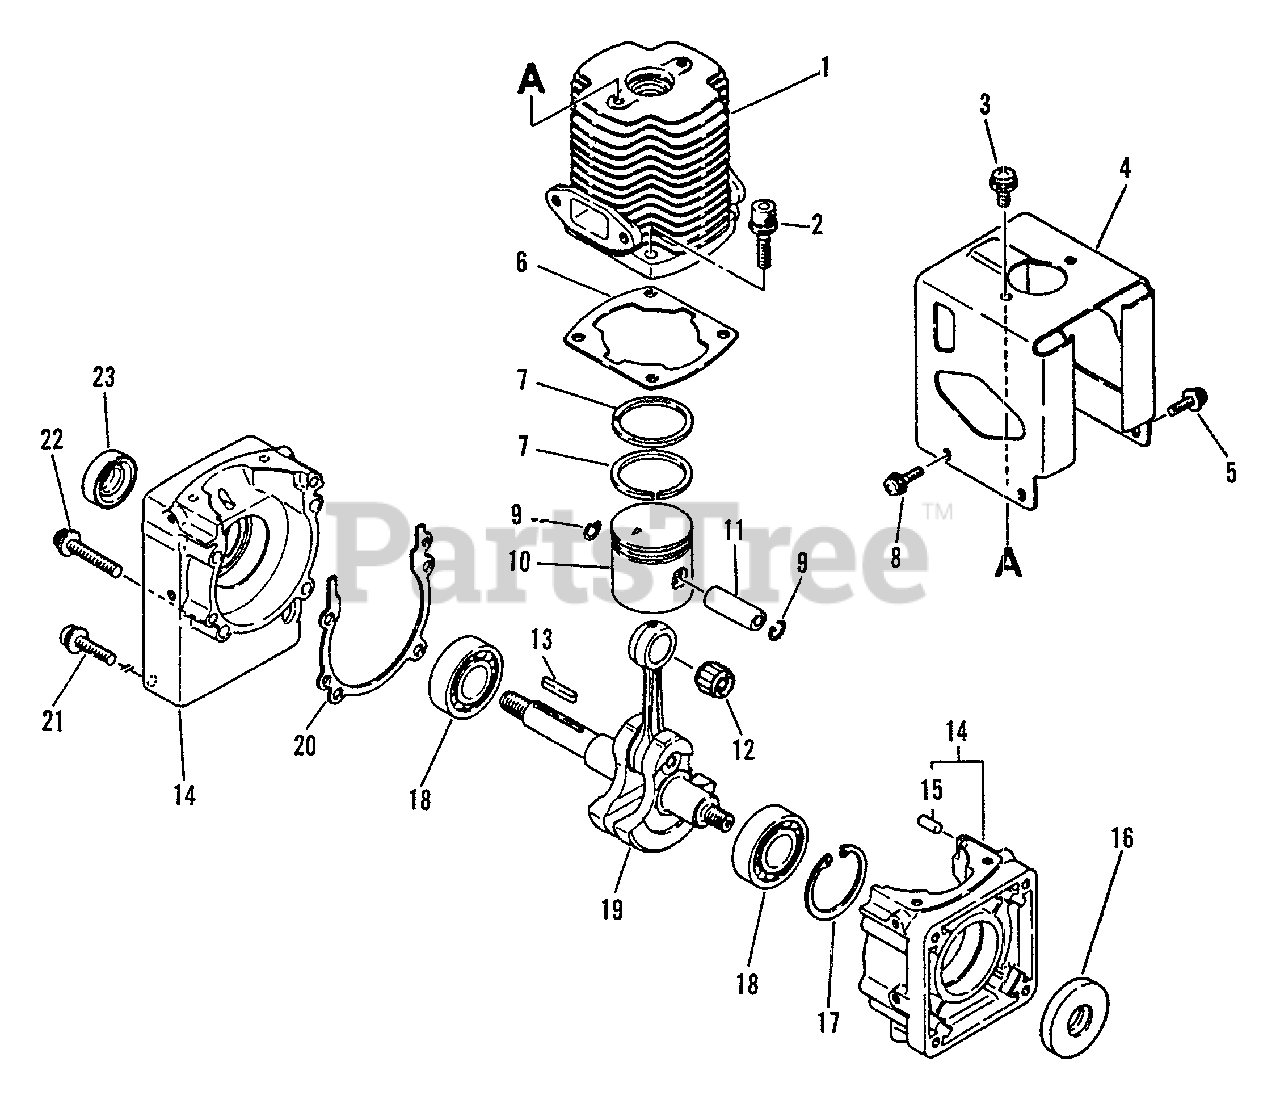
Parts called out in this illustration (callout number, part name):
1	CYLINDER
2	SCREW - 5X20
3	SCREW - 5X10
4	SHIELD, CYLINDER
5	SCREW - 4X14
6	GASKET, CYLINDER
7	RING, PISTON
8	SCREW - 4X12
9	RING, RETAINING - 8
10	PISTON
11	PIN, PISTON
12	BEARING, NEEDLE
13	KEY
14	CRANKCASE KIT
15	PIN - LOCATING
16	SEAL, OIL
17	RING, RETAINING - 35
18	BEARING, BALL - 6202
19	CRANKSHAFT ASSY
20	GASKET, CRANKCASE
21	SCREW - 5X20
22	SCREW - 5X30
23	SEAL, OIL
